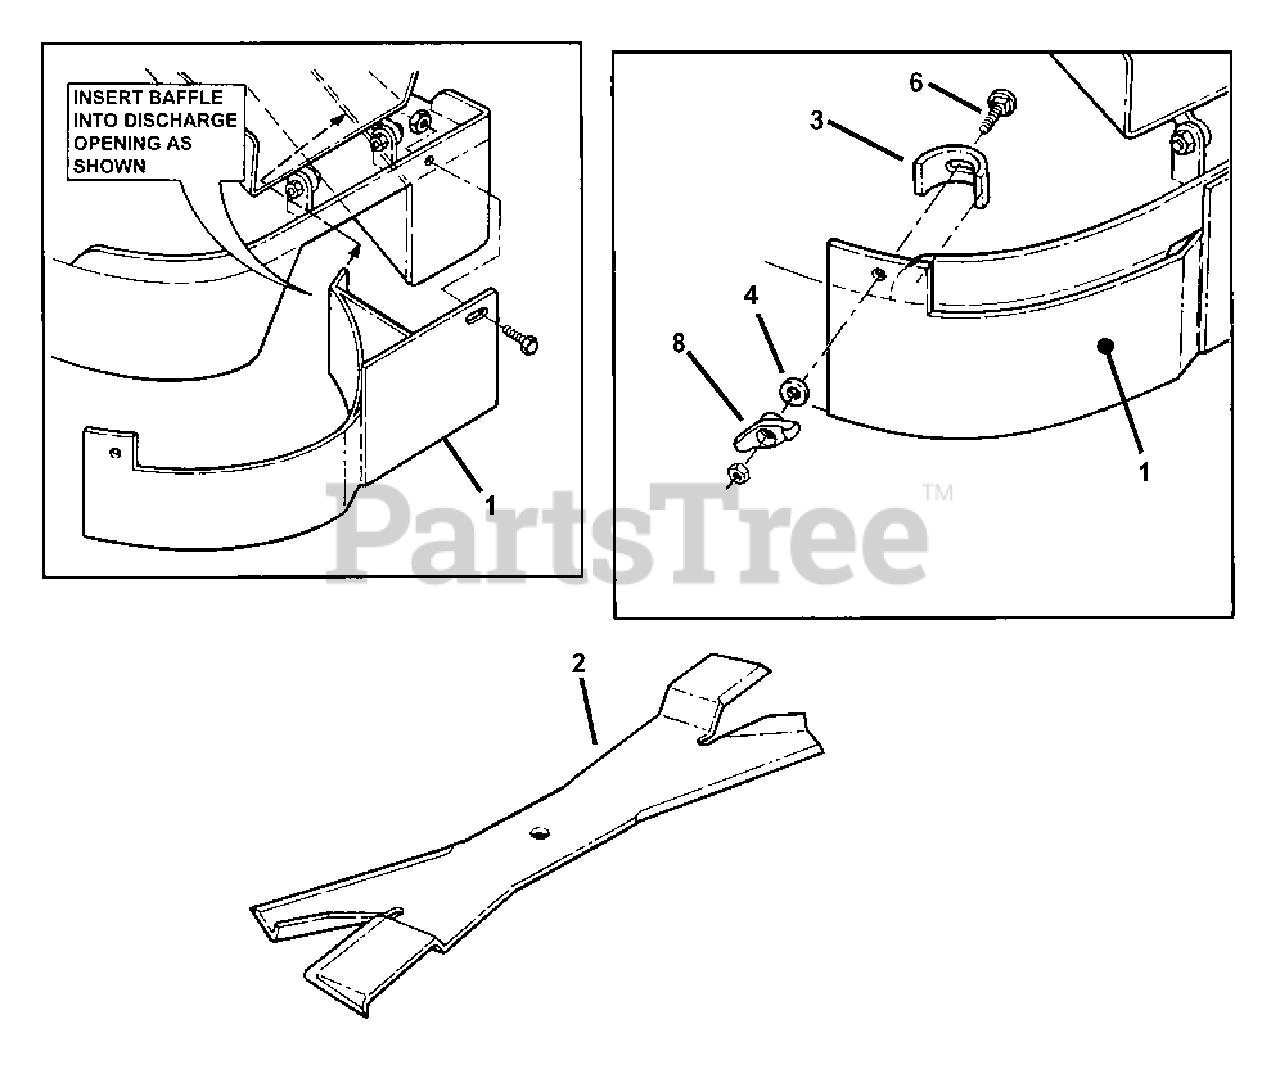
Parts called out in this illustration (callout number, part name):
1	WELDMENT, 48" Recycling Baffle
2	BLADE, 16-1/2" Quad Edge
3	CLAMP
4	WASHER, 5/16" Flat
6	BOLT, 5/16-18 x 1-1/2" Square Neck Carriage, Grade 5
8	T-KNOB, Plastic
